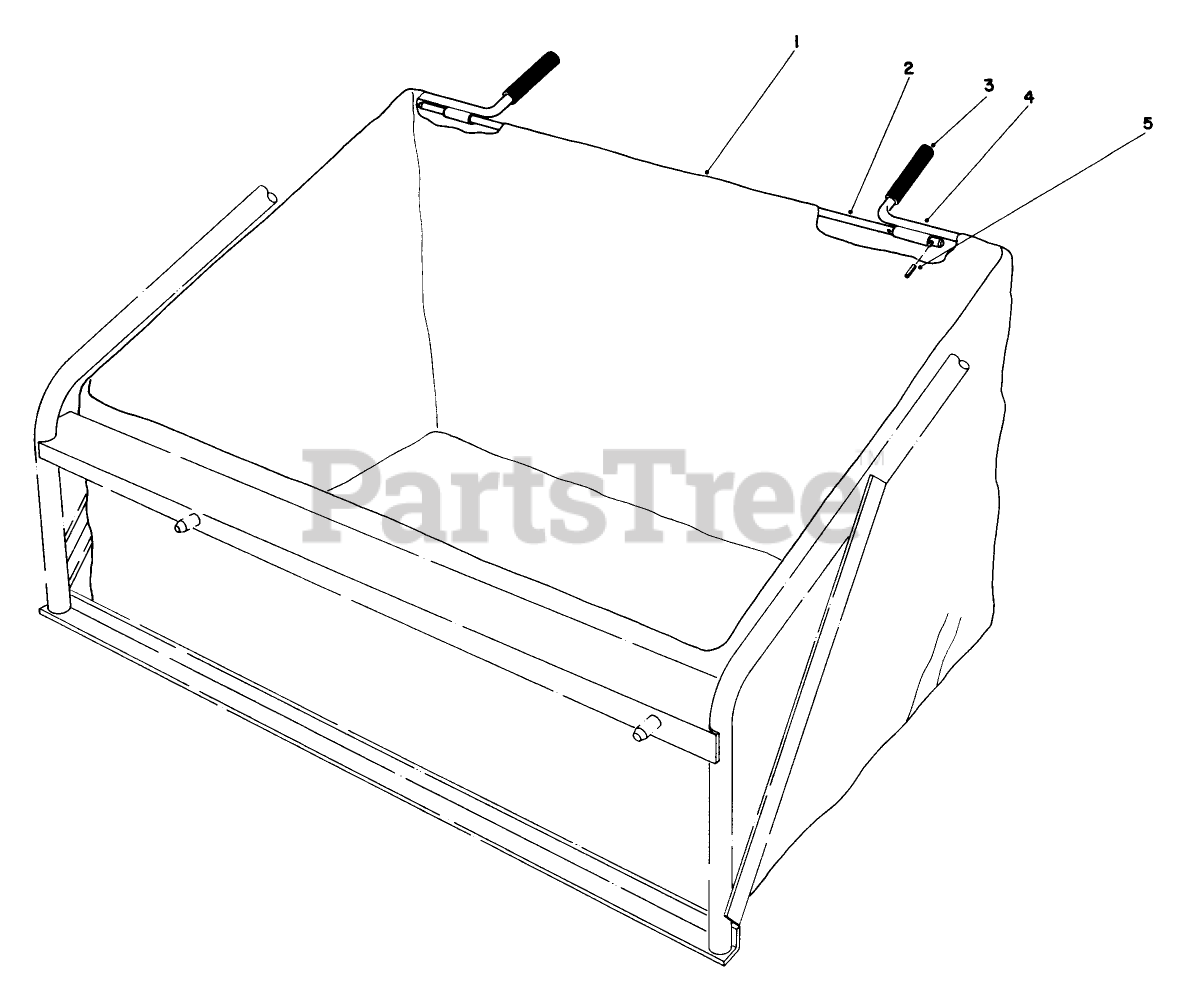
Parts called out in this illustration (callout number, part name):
2	Rod-Bag Frame
4	BAG FRAME WA *B
5	PIN-ROLL
